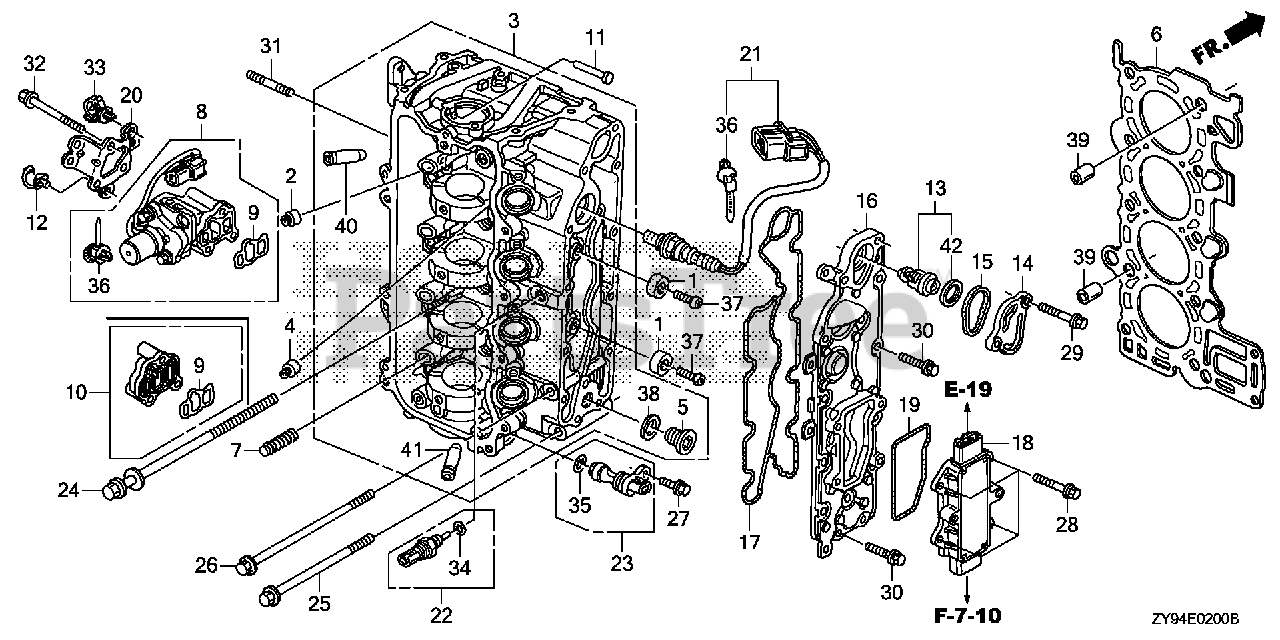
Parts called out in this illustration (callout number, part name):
1	METAL, ANODE
2	SEAL A, VALVE STEM (NOK)
3	CYLINDER HEAD *NH8* (DARK GRAY)
4	SEAL B, VALVE STEM (NOK)
5	BOLT, SEALING (20MM)
6	GASKET, CYLINDER HEAD
7	MOTION, LOST
8	VALVE ASSY., SPOOL *NH8* (DARK GRAY)
9	FILTER ASSY., SPOOL VALVE
11	LIFTER, FUEL PUMP
12	CLAMP B, FUEL TUBE
13	THERMOSTAT ASSY.
14	COVER, THERMOSTAT
15	O-RING, THERMOSTAT COVER
16	COVER, WATER JACKET
17	GASKET, EX. WATER JACKET COVER
18	RECTIFIER ASSY., REGULATOR
19	GASKET, REGULATOR
20	BRACKET D, HARNESS CLIP
21	SENSOR, OXYGEN
22	SENSOR ASSY., WATER TEMPERATURE
23	SENSOR ASSY., TDC
24	BOLT-WASHER (9X155)
25	BOLT, FLANGE (8X95)
26	BOLT, FLANGE (8X110)
27	BOLT, FLANGE (6X16)
28	BOLT, FLANGE (6X20)
29	BOLT, FLANGE (6X35)
30	BOLT, FLANGE (6X22)
31	BOLT, STUD (8X32)
32	BOLT, FLANGE (6X55)
33	CLIP, HARNESS
34	O-RING (9.5X1.9)
35	O-RING (15X1.9)
36	CLIP, HARNESS BAND (145MM) (BLACK)
37	SCREW, PAN (6X18)
38	WASHER, DRAIN PLUG (20MM)
39	PIN, DOWEL (14X20)
40	GUIDE, VALVE (OVER SIZE)
41	GUIDE, EX. VALVE (OVER SIZE)
42	RUBBER, RING
